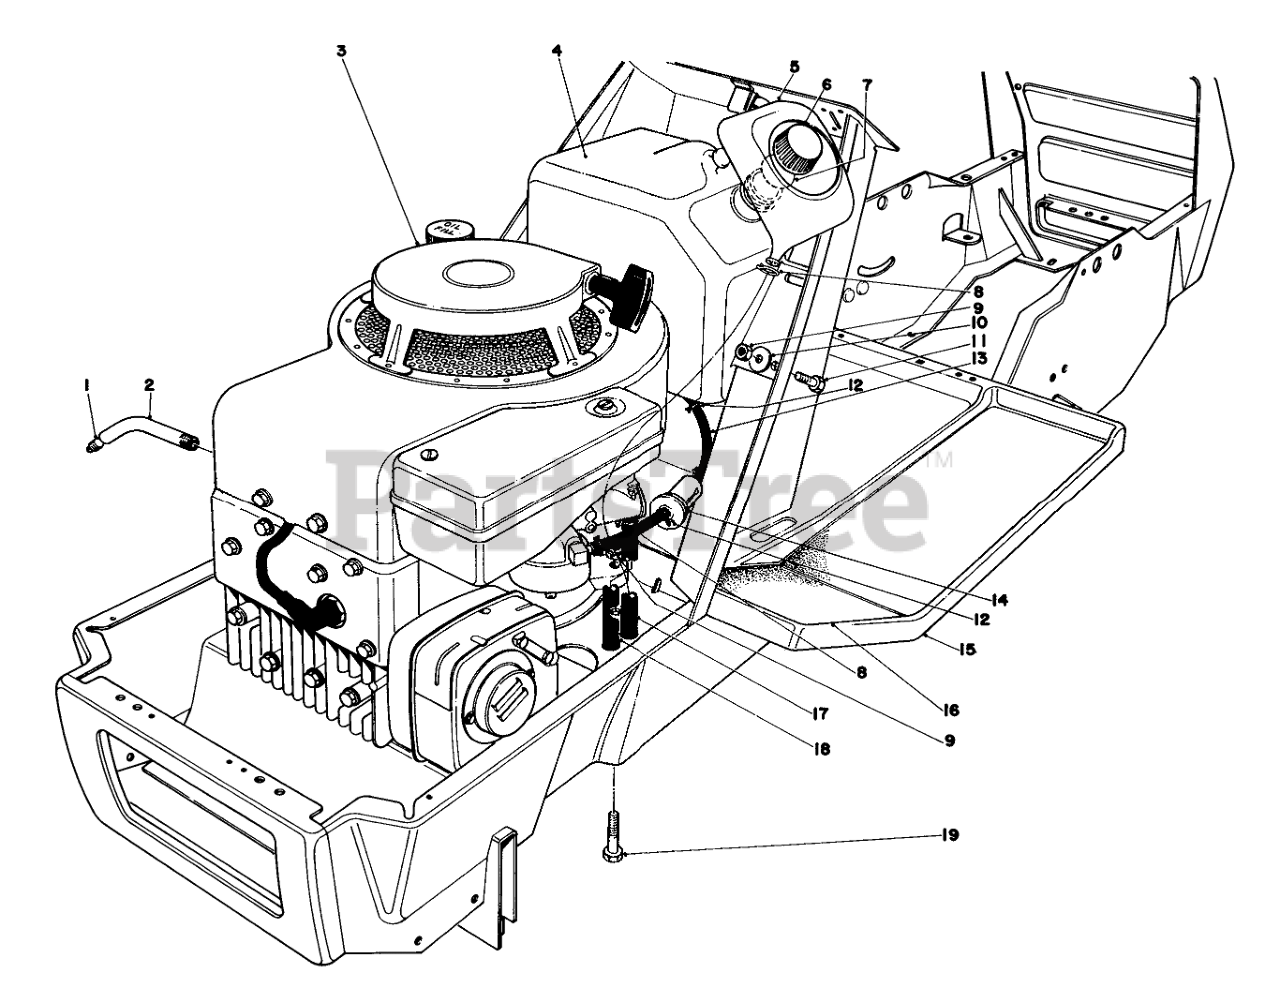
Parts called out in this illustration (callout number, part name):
1	PLUG-PIPE, SQH
2	OIL DRAIN TUBE
3	Engine
4	Gas Tank (Incl. Ref. #5)
5	Funnel-Overflow
6	Gas Cap (Incl. Ref. #7)
7	Gasket Gas Cap
8	HOSE CLAMP
9	NUT-LOCK, CONE
10	WASHER
11	SCREW-HH
12	Clamp
13	GAS HOSE
14	FUEL FILTER
15	Frame
16	LH FOOT TREAD
17	Hose Funnel
18	Hose Carburetor Drain
19	SCREW-HH
